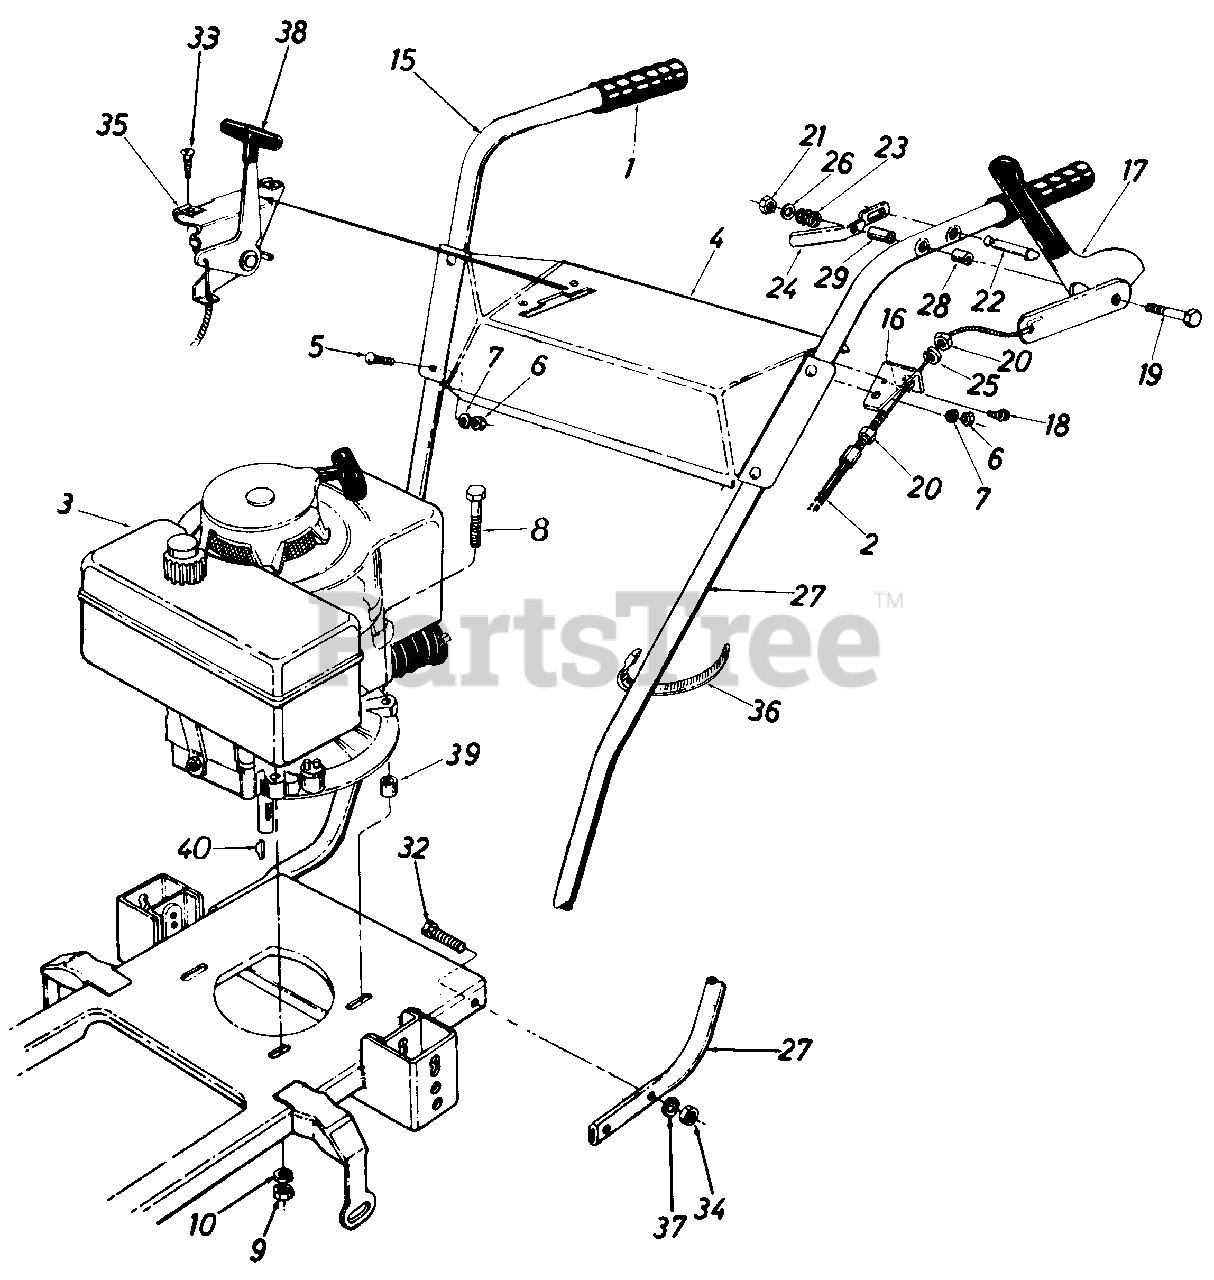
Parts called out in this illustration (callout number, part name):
2	Clutch Cable-39.0"
3	Engine
4	Handle Panel
5	Carr. Bolt 5/16-18 x 1.75" Lg.
6	Hex Nut 5/16-18 Thd.
7	L-Wash. 5/16" I.D.
8	Hex Bolt 5/16-24 x 1.75" Lg.
9	Hex Nut 5/16-24 Thd.
10	L-Wash. 5/16n I.D.
15	Handle-R.H.
16	Clutch Cable Brkt.
17	Blade Clutch Grip Ass'y.
18	Hex Wash. S-Tap Scr. 1/4-20 x .50" Lg.
19	Hex Bolt 1/4-20 x 2.25n Lg.
20	Hex Jam Nut 5/16-24 Thd.
21	Hex Cent. L-Nut 1/4-20 Thd.
22	Lock Pin
23	Compression Spring
24	Lockout Spring
25	L-Wash. 5/16n I.D.*
26	Internal Tooth L-Wash.
27	Handle-L.H.
28	Spacer.44" Lg.
29	Spacer 1.03" Lg.
32	Hex Bolt 5/16-24 x 1.25n Lg.
33	Hex Wash. Hd. AB-Tap Scr. #10 x .50" Lg.
34	Hex Nut 5/16-24 Thd.
35	Speed Nut 10Z U-Type
36	Cable Tie
37	L-Wash. 5/16" I.D.
38	Throttle Control
39	Spacer
40	Woodruff Key 5/32" x 5/8" Dia.
